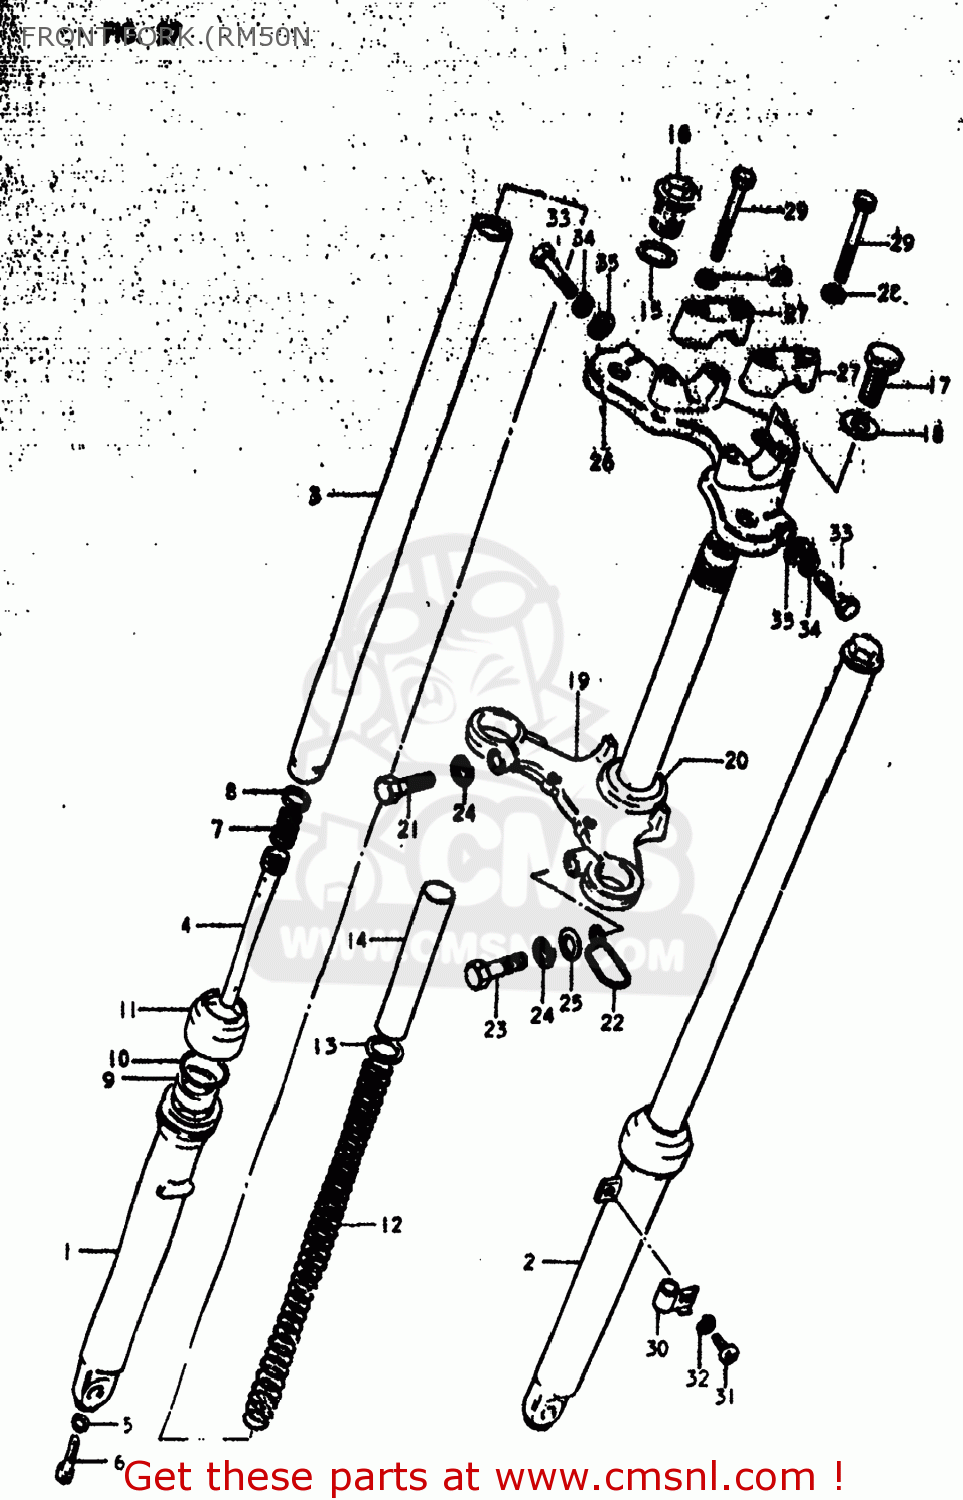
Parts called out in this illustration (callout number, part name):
1	TUBE,OUTER,RIGHT
2	TUBE,OUTER,LEFT
3	TUBE,FORK,INNER
4	CYLINDER,FRONT FORK
5	GASKET (NAS)
6	BOLT(8X27)
7	SPRING,REBOUND
8	RING,PISTON
9	OIL SEAL,FRONT FORK
10	CIRCLIP,FORK OIL SEAL
11	DUST SEAL
12	SPRING
13	JOINT,SPRING
14	SPACER,SPRING
15	O-RING,FORK INNER TUBE
16	CAP,FORK
17	BOLT
18	WASHER(10.5X30X2.3)
19	STEM,STEERING
20	RACE,STEERING OUTER LWR
21	BOLT 10X30
22	CLAMP,METER CABLE
23	BOLT,M10X1.25X
24	LOCK WASHER
25	WASHER
26	HEAD,STEERING STEM
27	HOLDER,HANDLEBAR
28	LOCK WASHER
29	BOLT
30	CLIP,CABLE
31	SCREW
32	LOCK WASHER
33	BOLT 8X40
34	LOCK WASHER
35	WASHER
